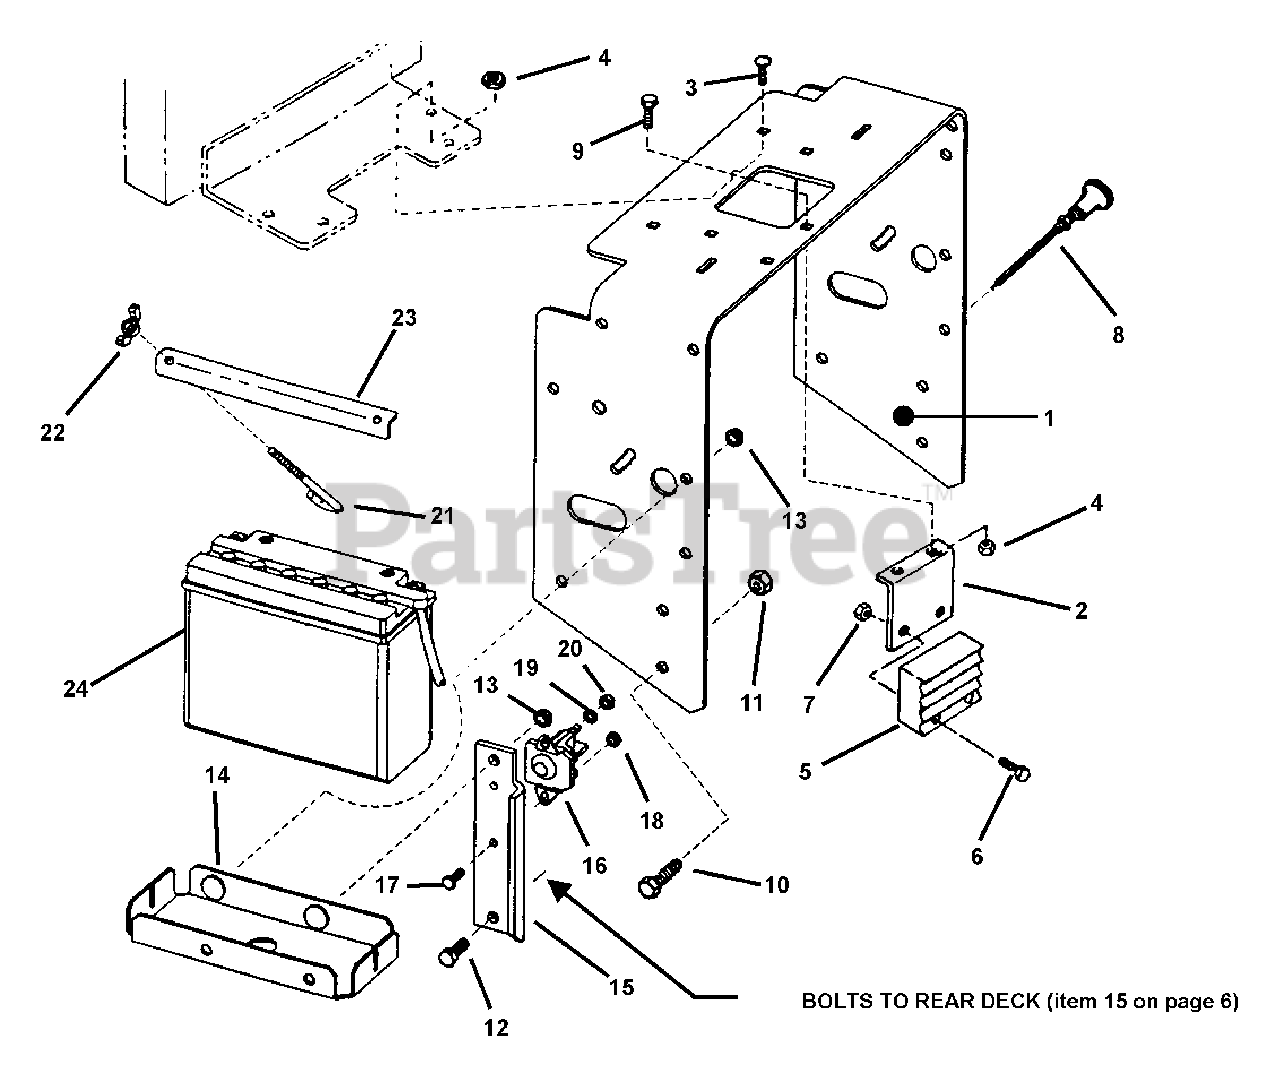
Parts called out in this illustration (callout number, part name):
1	BRACKET, Hydraulic Tank
2	BRACKET, Regulator
3	SCREW, 5/16-18 x 3/4", Round Head Machine
4	NUT, 5/16-18 HEX NYLON LOCK
5	REGULATOR/RECTIFIER
6	BOLT, 1/4-20 X 1" GD5 CZ
7	NUT, 1/4-20 Hex Nyloc
8	CABLE, Choke
9	BOLT, 5/16-18 X 1 GD5 YZ
10	BOLT, 3/8-16 x 1" Hex Flange Lock
11	NUT, 3/8-16 HEX NYLON LOCK
12	BOLT, 3/8-16 X 1" GD5 CZ
13	NUT, 3/8-16, HEX TOP LOCK
14	TRAY, Battery
15	BRACE, Battery
16	SOLENOID, 12 Volt
17	SCREW, 1/4-20x3/4",Gr. 5
18	NUT, 1/4-20 Hex Top Lock
19	WASHER, 1/4" Int. Tooth Lock
20	NUT, Battery Terminal
21	J-BOLT
22	WING LOCKNUT, 5/16-18
23	STRAP, Battery Clamp
24	KIT, Battery
